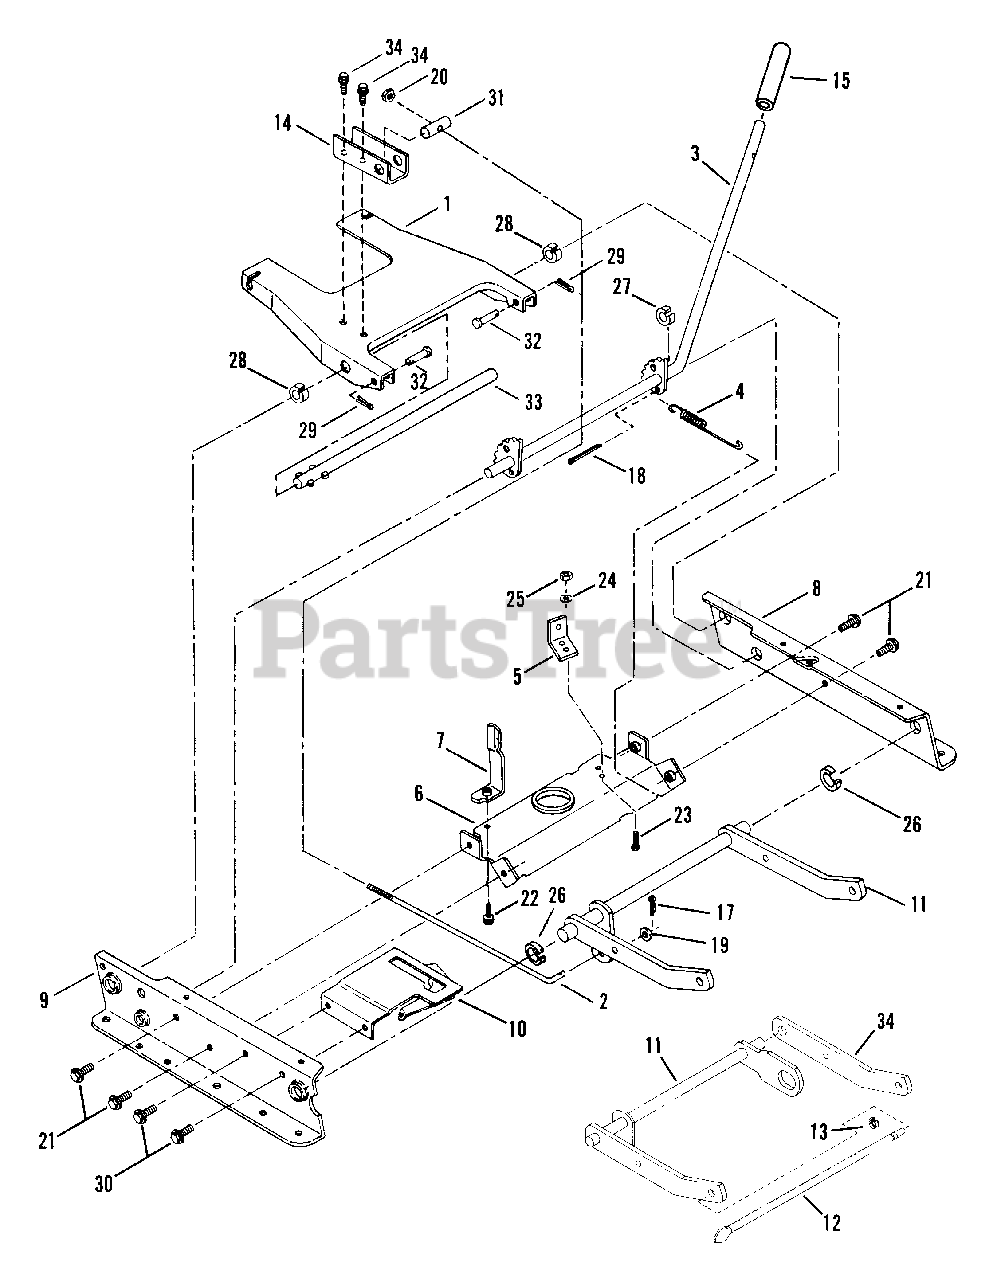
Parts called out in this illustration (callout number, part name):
1	ARM, Rear Lift
2	ROD, Leveling
3	WELDMENT, Lift Lever
4	SPRING, Cam Lever
5	ANCHOR
6	BRACE, Top
7	GUIDE, Belt
8	RAIL, Left Hand
9	RAIL, Right Hand
10	ASSEMBLY, Clutch Plate
11	ARM, Front Lift, Non-Adjustable
12	ROD, Support (Front Lift Arm to Front End)
13	RING, 7/16 Retaining
14	ARM, Leveling
15	GRIP, Height Adjustment Lever
17	PIN, 1/8 x 3/4" Cotter
18	PIN, 5/32 x 1" Cotter
19	WASHER, 3/8" Flat
20	NUT, 3/8-24 Hex
21	SCREW, 3/8-16 x 1/2" Self-Tapping
22	SCREW, 5/16-18 x 5/8" Self-Tapping
23	SCREW, 5/16-24 x 3/4" Hex Head Cap
24	WASHER, 5/16 Internal Tooth Lock
25	NUT, 5/16-24 Hex
26	RING, Red
27	RING, White
28	RING, White
29	PIN, 3/32 x 3/4" Cotter
30	SCREW, 5/16-18 x 1/2" Self-Tapping
31	PIVOT, Leveling
32	PIN, 3/8 x 1 1/16" Clevis
33	SHAFT, Pivot
34	ARM, Front Lift-Left
